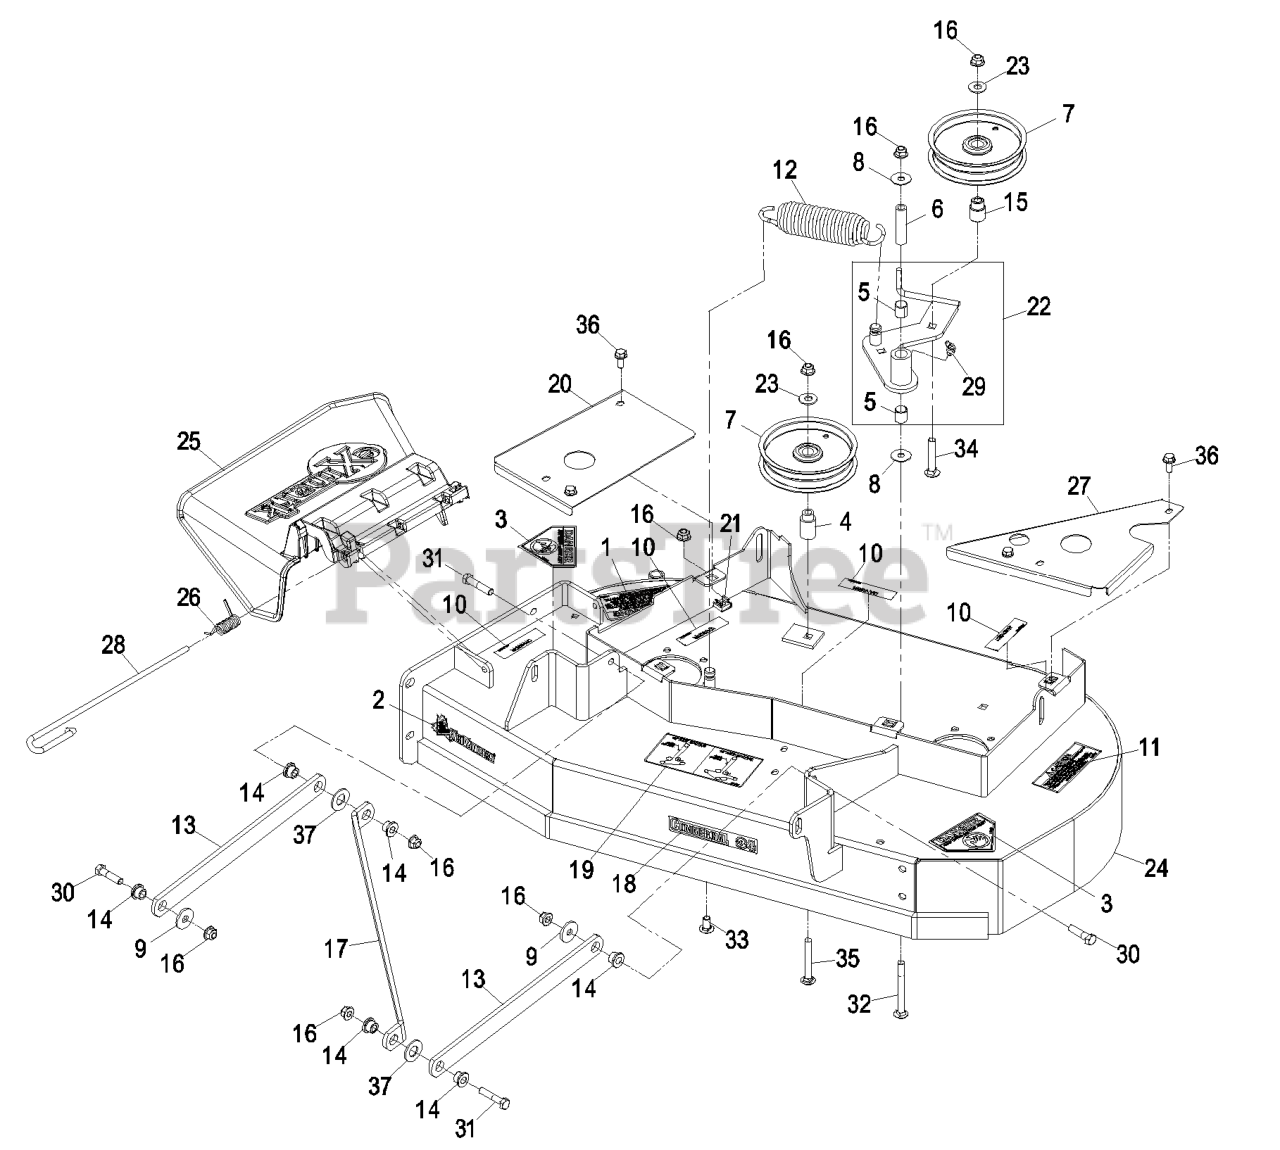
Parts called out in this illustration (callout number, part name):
1	DECAL-WARNING, DISCHARGE
3	DECAL-DANGER
4	BUSHING-IDLER
5	SLEEVE-BEARING
6	BUSHING-PIVOT, IDLER
7	PULLEY-IDLER
10	DECAL-COVER, MISSING
11	DECAL,BOLT TORQUE
13	FLAT,STRUT
14	SPACER-STRUT
15	BUSHING,IDLER
16	NUT-HF, NI
17	BRACE,DECK LINKAGE
18	DECAL,COMMERICAL 34
19	DECAL,BELT ROUTING 34/44
20	COVER,BELT RH
21	NUT,CAGE
22	ASM,IDLER DECK PHAZER
23	WASHER-FLAT
24	ASM,34 DECK WITH DECALS
25	CHUTE,DISCHARGE 34"
26	SPRING-TORSION
27	COVER,LEFT SPINDLE
28	PIN,CHUTE
29	FITTING-GREASE, 90 DEG
30	SCREW-HH
31	SCREW-HH
32	SCREW-CARR
33	SCREW-CARR
34	Bolt-Carriage 3/8-16 X 2 1/4
35	SCREW-CARR
36	SCREW-HHF
37	WASHER-FLAT
38	ASM,34 DECK COMPLETE
